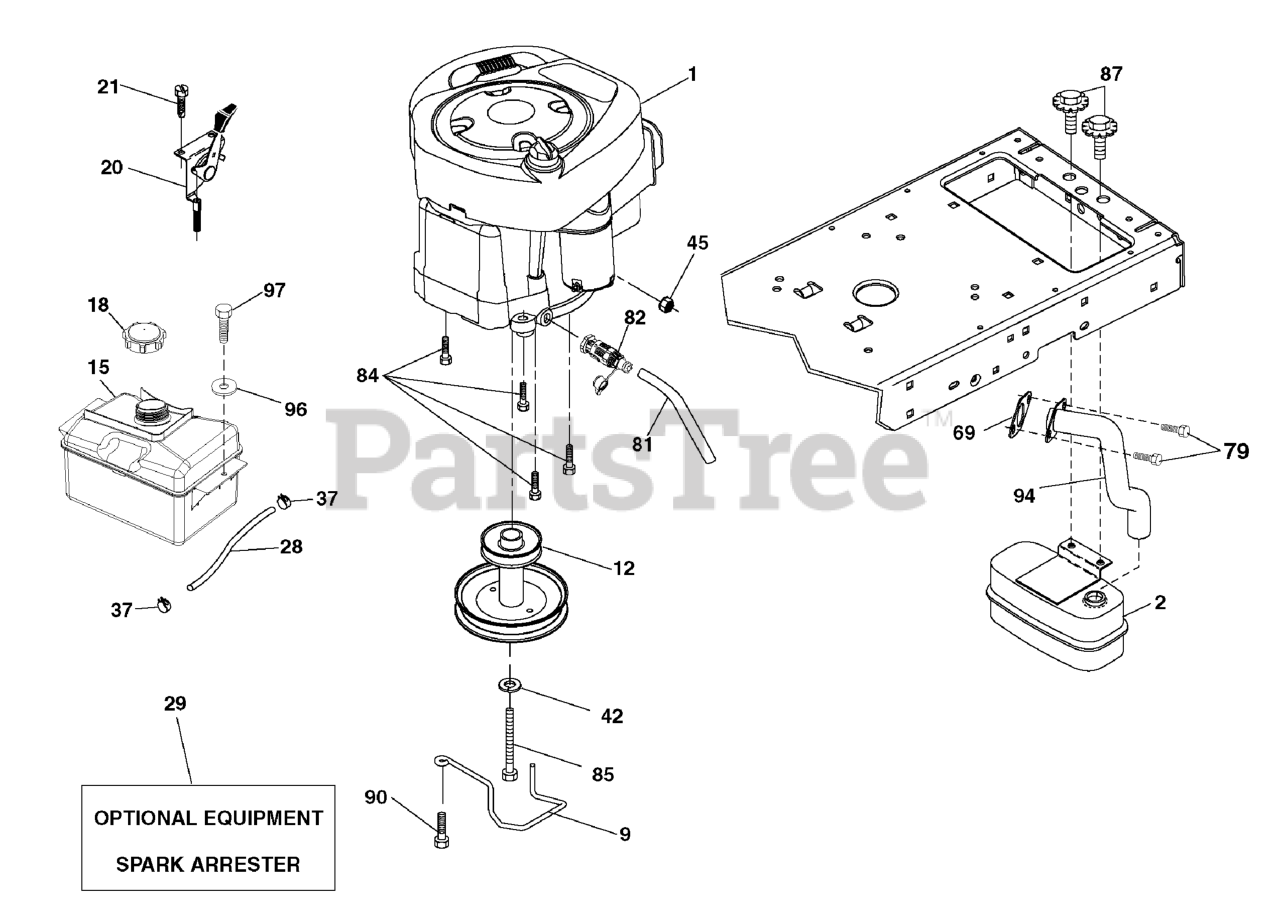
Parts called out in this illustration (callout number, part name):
1	* Engine, Briggs & Stratton
2	Muffler
9	Keeper Belt Engine
11	Clutch Electric
12	Pulley Engine
15	Tank Fuel
18	Cap Asm
20	Control Throttle
21	Screw #10 x 0.750
28	Fuel Line
29	Spark Arrester Kit
37	Clamp Hose
42	Washer Lock 7/16
45	Nut Keps Hex 1/4-20 unc
69	Gasket
79	Screw 5/16-18 x .75
81	Tube Drain Oil Easy
82	Valve Drain Oil
84	Screw 3/8-16 x 1-1/4
85	Bolt Hex 7/16-20 x 4 5 Ga. 1.5
87	Bolt 5/16-18 unc x 3/4 w/Sems
90	Screw 3/8-16 x 1
94	Exhaust Tube
96	Washer 9/32 x 7/8 x 16 Ga.
97	Screw 1/4-20 x 3/4
